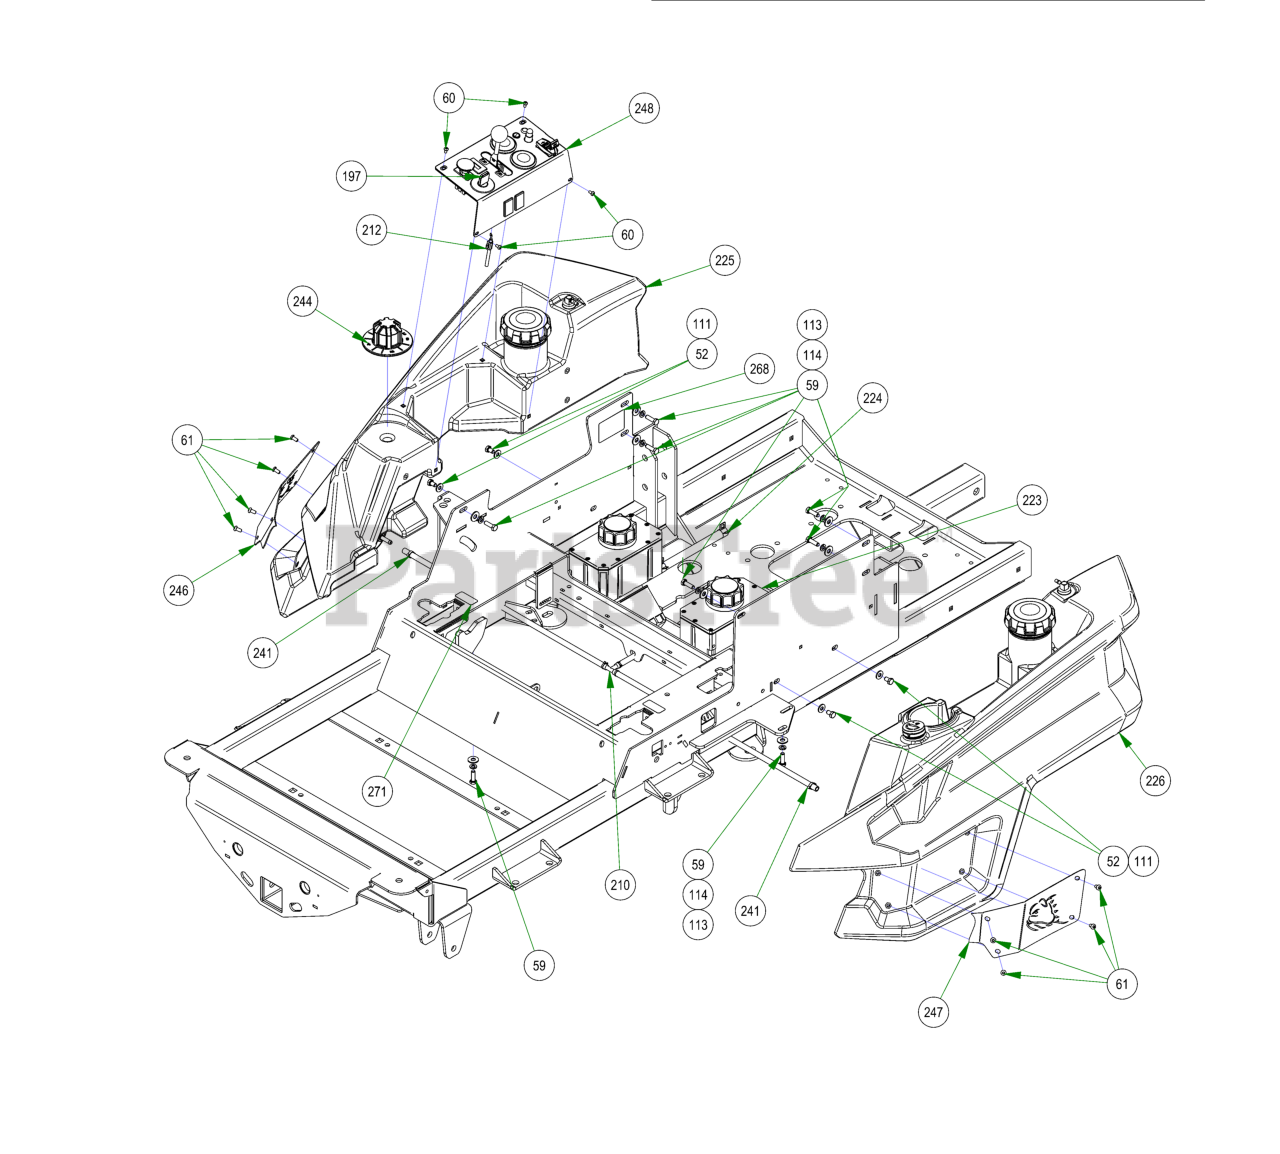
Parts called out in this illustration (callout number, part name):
52	5/16-18 X 1/2 HEX CAP SCREW (GR.5) ZINC
59	5/16-18 X 1 HEX CAP SCREW (GR.5) ZINC
60	10-32 X 3/8 BUTTON SOCKET CAP SCREW 18-8 STAINLESS STEEL
61	1/4-20 X 1/2 BUTTON SOCKET CAP SCREW 18-8 STAINLESS STEEL
111	1/4 USS FLAT WASHER (3/4 OD) ZINC
113	5/16 USS FLAT WASHER (7/8 OD) ZINC
114	5/16 SPLIT LOCKWASHER ZINC
128	.380 ID X .625 OD X 1.500 LGTH 2019 OUTLAW BRAKE HANDLE SPACER ZINC
135	1 3/4" Pulley Spacer
197	Ignition Key
210	2022 Renegade Diesel Fuel Line Assembly
212	Diesel Throttle Cable
223	LH Rogue Hydro Tank Assy
224	RH Rogue Hydro Tank Assy
225	2019 Right Renagade Fuel Tank (diesel)
226	2019 Left Renegade Fuel Tank (Diesel)
234	2022 Horizontal Diesel Frame
241	2 EAR CLAMP 12.5mm-15mm
244	2019 Deck Height Dial
246	2019 Outlaw Fuel Tank Insert - Right
247	2019 Outlaw Fuel Tank Insert - Left
248	Renegade Control Panel Assembly
268	Hydraulic Decal
271	Low Sulfer Decal Tier 4 Diesel
